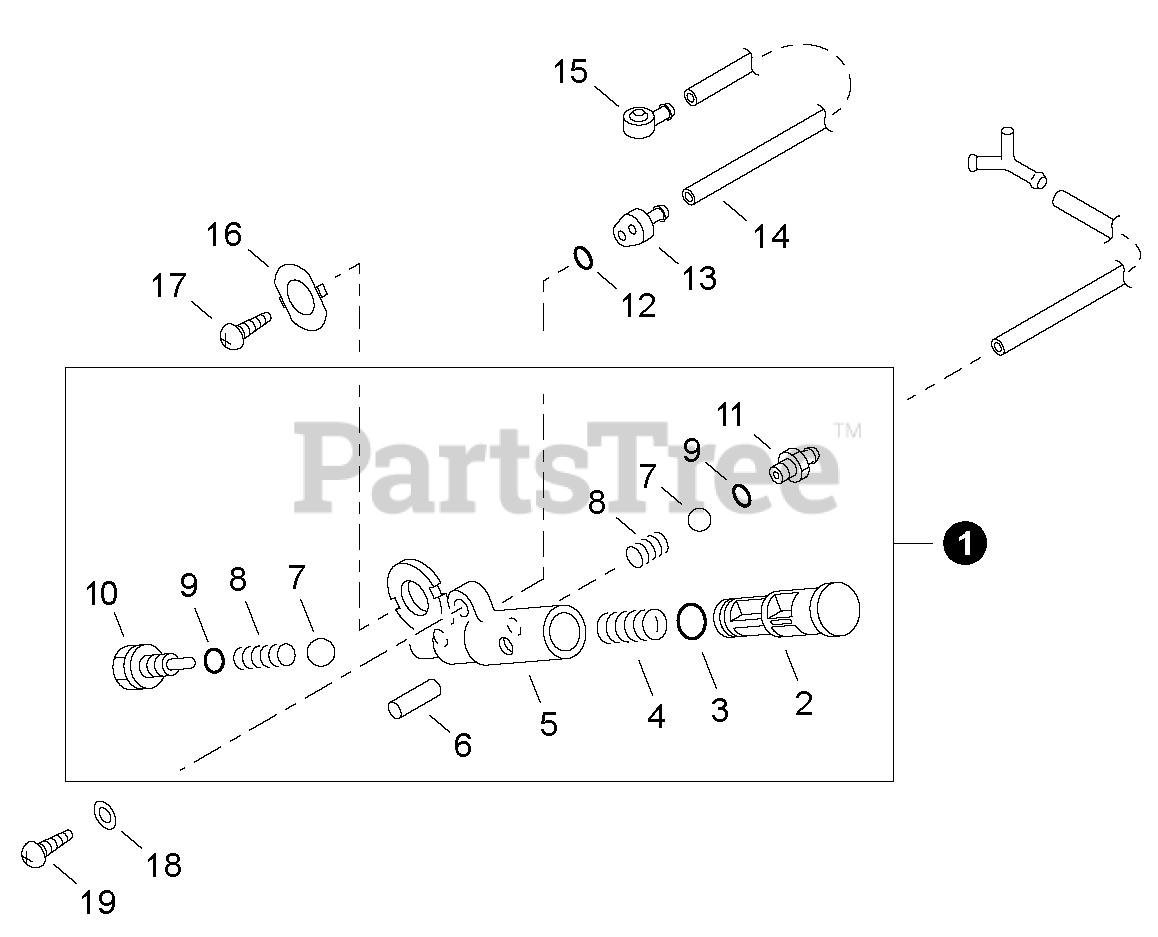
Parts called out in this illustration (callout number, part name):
1	OIL PUMP ASSY
2	PISTON, OIL PUMP
3	O-RING - 7
5	BODY, OIL PUMP
6	PIN - SPRING -- 2X16
7	VALVE, BALL
10	ADAPTOR, OIL PUMP
11	CONNECTOR, PIPE
12	O-RING - 3
13	CONNECTOR, PIPE
14	TUBE, OIL - 3×6×125
15	CONNECTOR, PIPE
16	BRACKET, OIL PUMP
17	SCREW - 4X10
18	WASHER - 5
19	SCREW - 5X20
